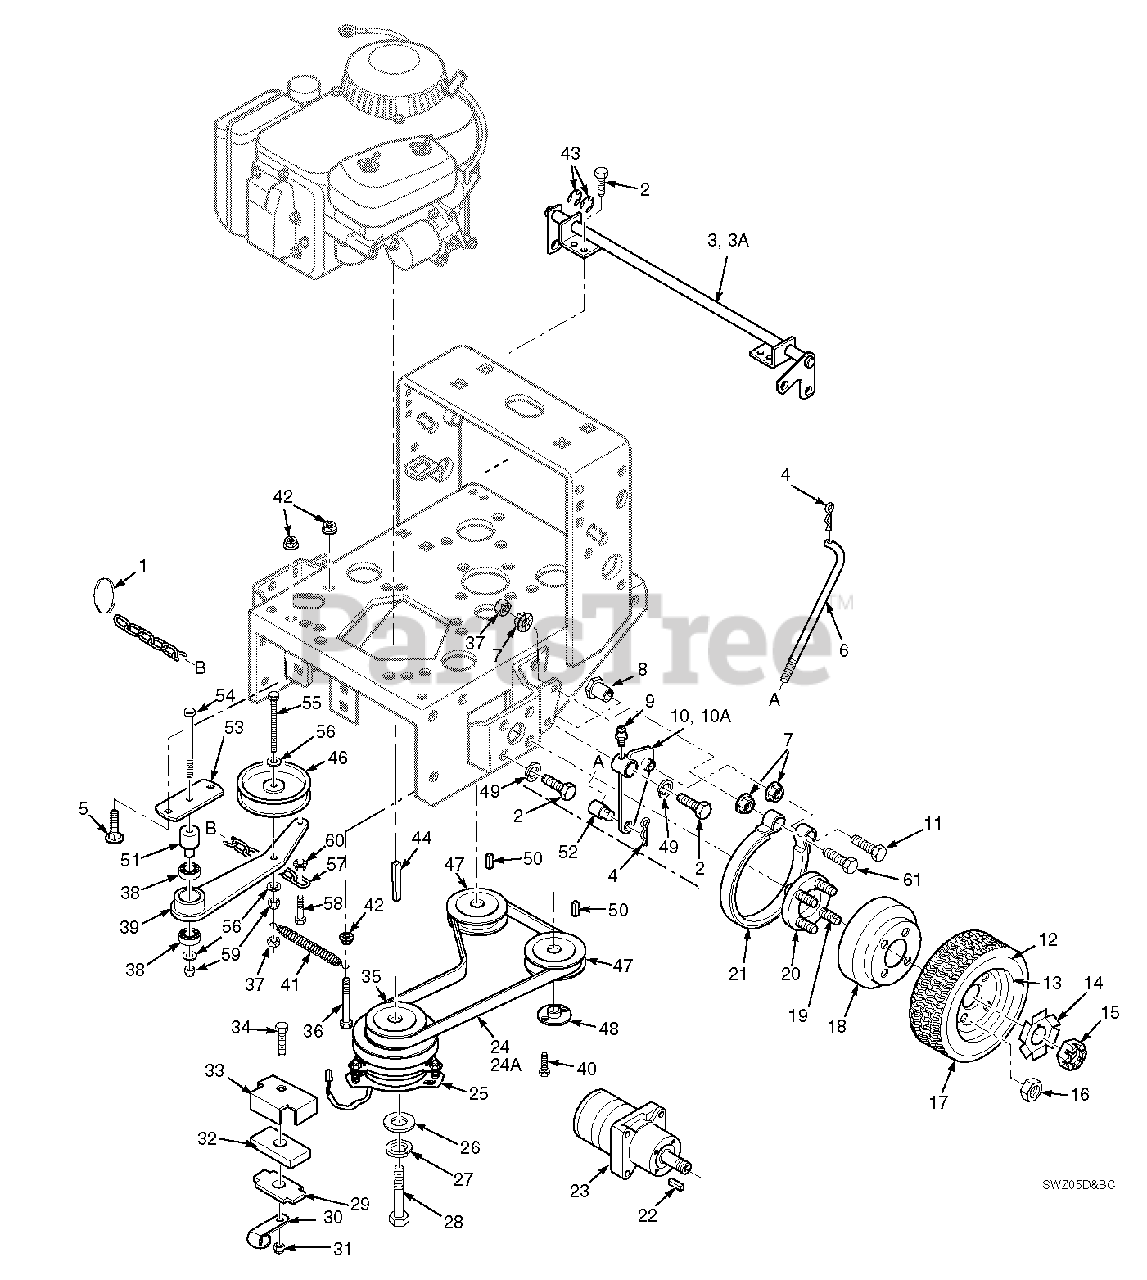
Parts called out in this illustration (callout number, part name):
1	Ring, Split
2	Bolt, 3/8-16 x 1" Hex Head
3	Brake Shaft Assembly Weldment, 16" Small Frame
3A	Brake Shaft Assembly Weldment, 20" Large Frame
4	Hair Pin Cotter, .094 x 1.62
5	Carrage Bolt, 5/16-18 x .75"
6	Rod, Brake Lower
7	Nut, 3/8-16 Serr. Flange
8	Bushing, Brake
9	Grease Fitting
10	Brake Actuator Weldment-LH
10A	Brake Actuator Weldment-RH
11	Bolt, 3/8-16 x 2-1/4"
12	Tire, 16 x 6.50, 4 ply
13	Rim Assy
14	Lock Washer, Wheel Motor
15	Hex Castle Nut, 3/4-28 UNEF
16	Nut, Lug
17	Wheel Assy
18	Brake Drum
19	1/2-20 Serrated Bolt
20	Hub, Wheel
21	Brake Band, 7.5"
22	Key, 3/16 X .75 Woodruff
23	Wheel Motor
24	Belt, Pump Drive, 16" Small Frame
24A	Belt, Pump Drive, 20" Large Frame
25	Electric Clutch
26	Flat Washer .469 x 1.75 x .25
27	Lock Washer, 7/16"
28	Hex Head Bolt, 7/16-20 x 2-3/4"
29	Plate, Backing
31	Nut, 5/16-18 Elastic Stop
32	Rubber Pad, Clutch Stop
33	Retainer, Clutch Stop
34	Hex Head Bolt, 5/16-18 x 1.75"
35	Pulley, Pump Drive Engine
36	Hex Head Bolt, 5/16-18 x 2.75"
37	Nut, 3/8-16 Center Lock
38	Ball Bearings
39	Idler Arm Weldment, Pump
40	Bolt, Hex Head 1/4-20 x 1" Grd 8
41	Spring, Pump Belt Idler
42	Nut, 5/16-18 Serr. Flange
43	Retaining Ring, 3/4" Ext. "E"
44	Key, 1/4x1/4 x 3.75"
45	Flat Washer, 3/8"
46	Pulley, Idler 4.5"
47	Pulley, Pump Shaft
48	Tapered Hub
49	Lockwasher, 3/8"
50	Key, 5.0 x 5.0 x 25mm
51	Pivot, Idler
52	Swivel Joint
53	Base, Idler Pivot
54	Bolt, Hex Head 3/8-16 x 3"
55	Bolt, Hex Head 3/8-16 x 2.75"
56	Flatwasher 3/8"
57	Chain
58	Bolt, Hex Head 1/4-20 x 1.25"
59	Nut, Hex Elastic Stop 3/8-16
60	Nut, Serrated Flange 1/4-20
61	Bolt, Hex Head 3/8-16 x 2.63"
